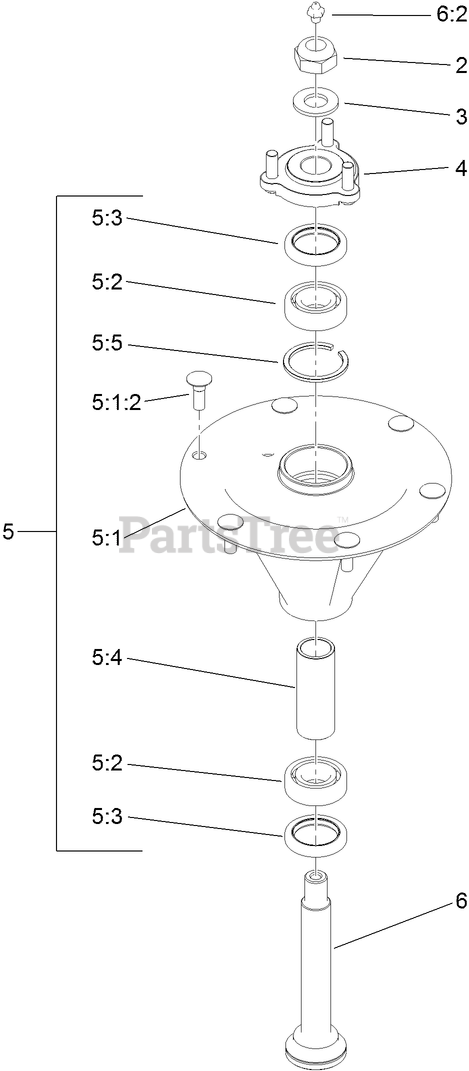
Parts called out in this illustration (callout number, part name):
2	NUT-LOCK, NI
3	WASHER
4	SPINDLE HUB ASM
5	SPINDLE HOUSING ASM
5:1	SPINDLE HOUSING AND STUDS ASM
5:1:2	BOLT-RIBBED NECK
5:2	BEARING -NOSEAL
5:3	SEAL-OIL
5:4	SPACER
5:5	SNAP RING
6	SHAFT-SPINDLE
6:2	FITTING-GREASE
